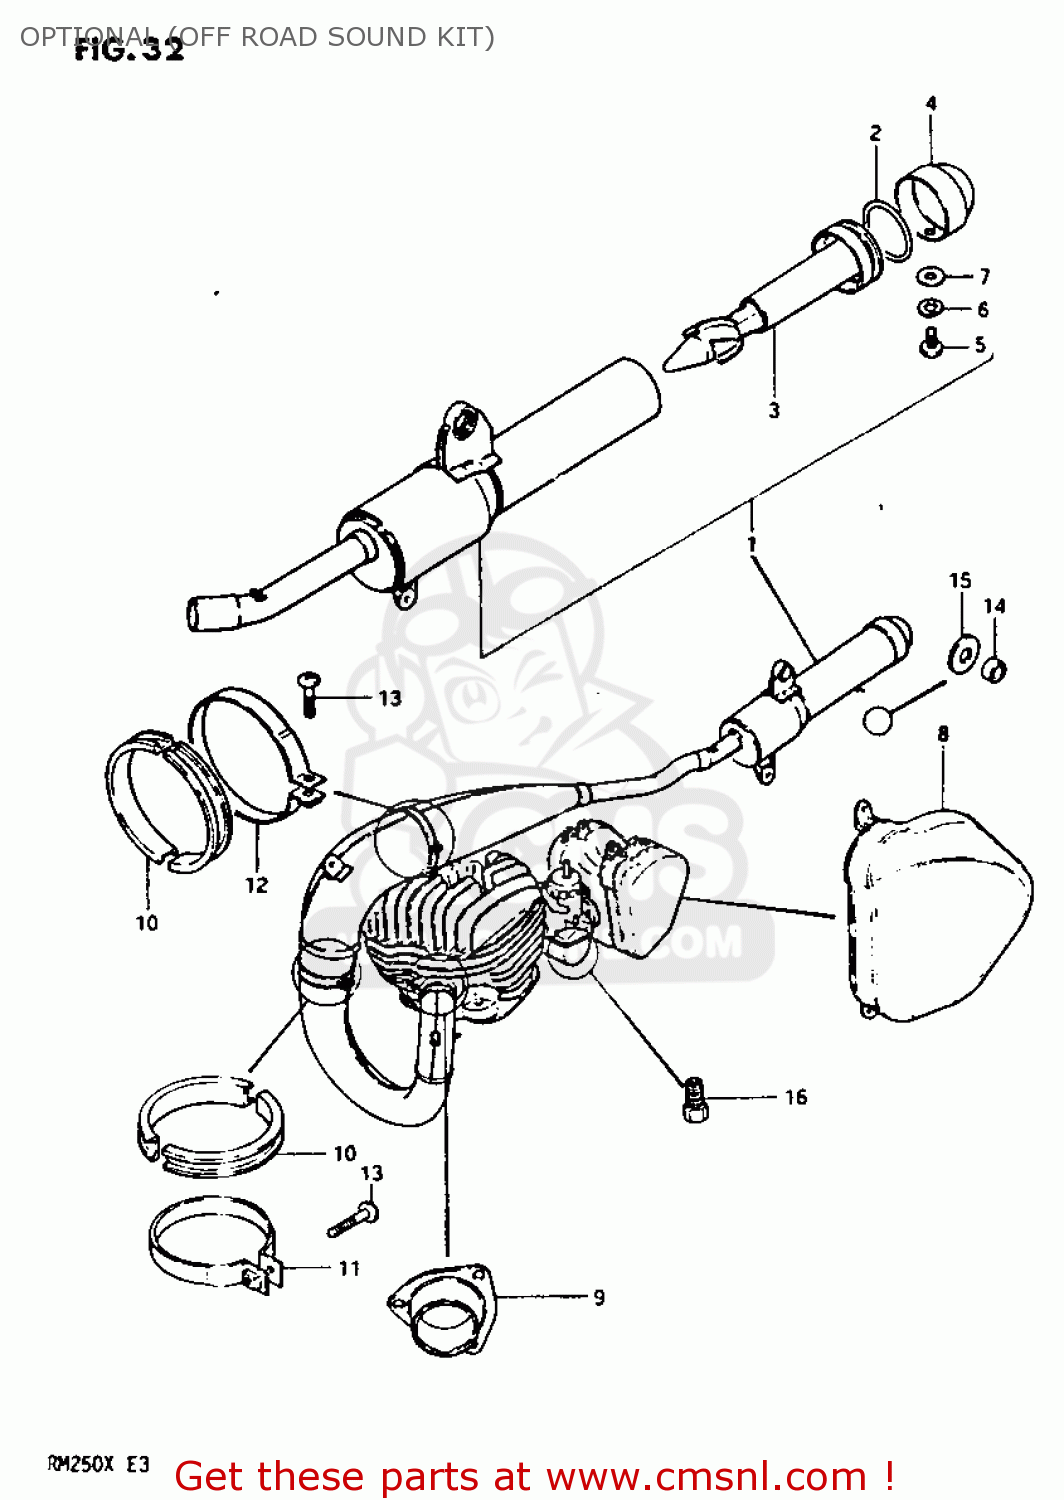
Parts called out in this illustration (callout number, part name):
1	MUFFLER ASSEMBLY
2	O-RING (D:3.5 ID:54.4)
3	TUBE,MUFFLER CLEAN OUT
4	COVER,SECOND MUFFLER TAIL
5	SCREW(6X8)
6	WASHER,LOCK
7	WASHER
8	COVER AIR CLEANER
9	FLANGE,EXHAUST PIPE
10	BODY,MUFFLER
11	CLAMP
12	CLAMP
13	SCREW
14	SPACER
15	GASKET
16	JET
